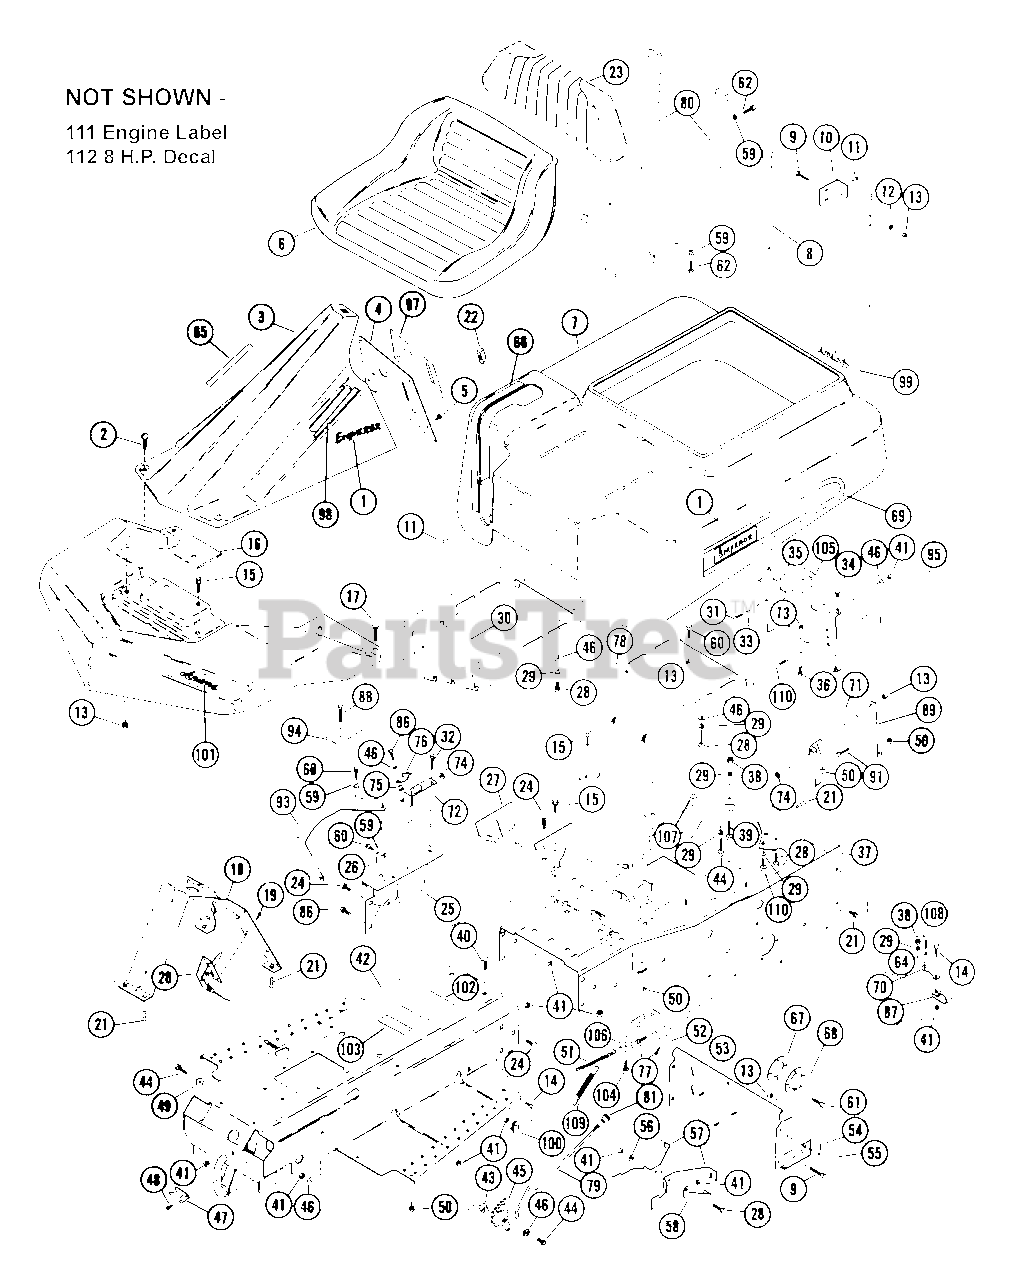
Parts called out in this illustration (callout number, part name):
1	EMPEROR NAME PLATE
2	SCR-MCH .25-20X.63 CRPH PL
4	DASH COVER ASSEMBLY
5	SCR-TAP 10-12X.50 CRPH PL A
6	SEAT
7	ENGINE COVER ASSEMBLY
8	SERVICE BAR
9	BLT-HEX .25-20X1.50 PL GR5
10	BRACKET
11	RVT-POP .187X.402 DOME ST
12	WSHR-FL-STL.312X.734X.065PL
13	NUT-LK-CTR .250-20 PL
14	BLT-HEX .31-18X.75 PL GR2
15	BLT-SERHFWH .25-20X.50 PL
16	FRONT WHEEL COVERS
17	SCR-SLTR-SERNK .25-20X.62 PL
18	CONTROL PANEL
19	SCR-TAP 10-24X.375 CRPH 1A
20	THROTTLE CONTROL
21	BLT-SERHFWH .31-18X.50 PL
23	SEAT BACK
24	BLT-RDHDSQSHNK .31-18X.50 YZ
25	SHIFT QUADRANT
26	CLIP
27	SEAT HINGE
28	BLT-HEX .31-18X1.50 PL GR2
29	WSHR-LK .312X.097 PL HVY
30	BRACKET
31	SCR-TAP 10-16X1.0 SLHP PL AB
32	SCR-TAP 10-24X.375 CRPH 1A
33	WSHR-FL-STL .250X.562X.049 PL
34	BUMPER GROMMET
36	BLT-HEX .25-20X.50 PL GR2
37	FRAME
38	NUT-HEX .312-18
39	BLT-HEX .31-18X1.25 PL GR2
40	BLT-RDHDSQNK .312-18X.62 PL
41	NUT-LK .312-18 GR A PL
42	FRONT FRAME ASSY.
43	SPACER -SHLD .344X.500X.469
44	BLT-HEX .31-18X1.00 PL GR 2
45	BRAKE LATCH
46	WSHR-FL-STL .38X.875X.083 PL
47	LOCK SPRING
48	SCR-TAP 10-12X.50 CRPH PL A
49	SPACER .344X1.000X.375
50	NUT-LK-FLG .250-20 PL
51	BRAKE CHAIN
52	BRACKET
54	PIN-HAIR INT .09X1.88 PL
55	PIN
56	WSHR-FL-STL .323X.625X.062 PL
57	BELT FINGER
58	BELT FINGER BRACE
59	WSHR-LK .250X.077 HVY PL
60	BLT-HEX .25-20X.50 PL GR2
61	SCR-TAP 8-32X.38 SL HWH PL 23
62	BLT-HEX .25-20X.75 PL GR2
63	WSHR-FL-STL .323X.625X.062 PL
64	WSHR-LK .375X.115 HVY PL
65	MOWER HEIGHT DECAL
66	SHIFT DECAL
67	GASKET
68	PIPE
68	EXHAUST PIPE
69	SHROUD DECAL
70	MUFFLER BRACKET
71	SHIELD
72	SWITCH HOUSING
74	GROMMET, .31 ID
75	BSHG, FLG .325X.499X.26X.88
76	CAM NO SCRAP
77	BLT-SERHFWH .25-20X.50 PL
78	SEAT BRACKET
79	PARKING BRAKE ROD
80	SEAT BRACE
86	BLT-SERHFWH .31-18X.75 PL
88	SCR-TAP 12-14X1.25 CROVH PL 1A
89	BRACE
91	BLT-HEX .25-20X.38 PL GR2
92	BLT-HEX .31-18X.50 PL GR2
93	SHIFT PANEL
95	BAFFLE
97	DASH DECAL
98	MOWER CLUTCH DECAL
99	DECAL
101	ARIENS NAME PLATE
102	CAUTION DECAL
103	PATENTS PENDING LABEL
104	BLT-RDHDSQNK .25-20X.62 PL
105	CLAMP
106	BRACKET
107	WSHR-FL-STL .328X.875X.062 PL
108	BLT-HEX .38-16X.75 PL GR2
109	SG-TENS .041X.35X2.11 WLD 8
110	BLT-HEX .31-18X.75 PL GR2
111	ENGINE LABEL
112	8 H P ENGINE DECAL
